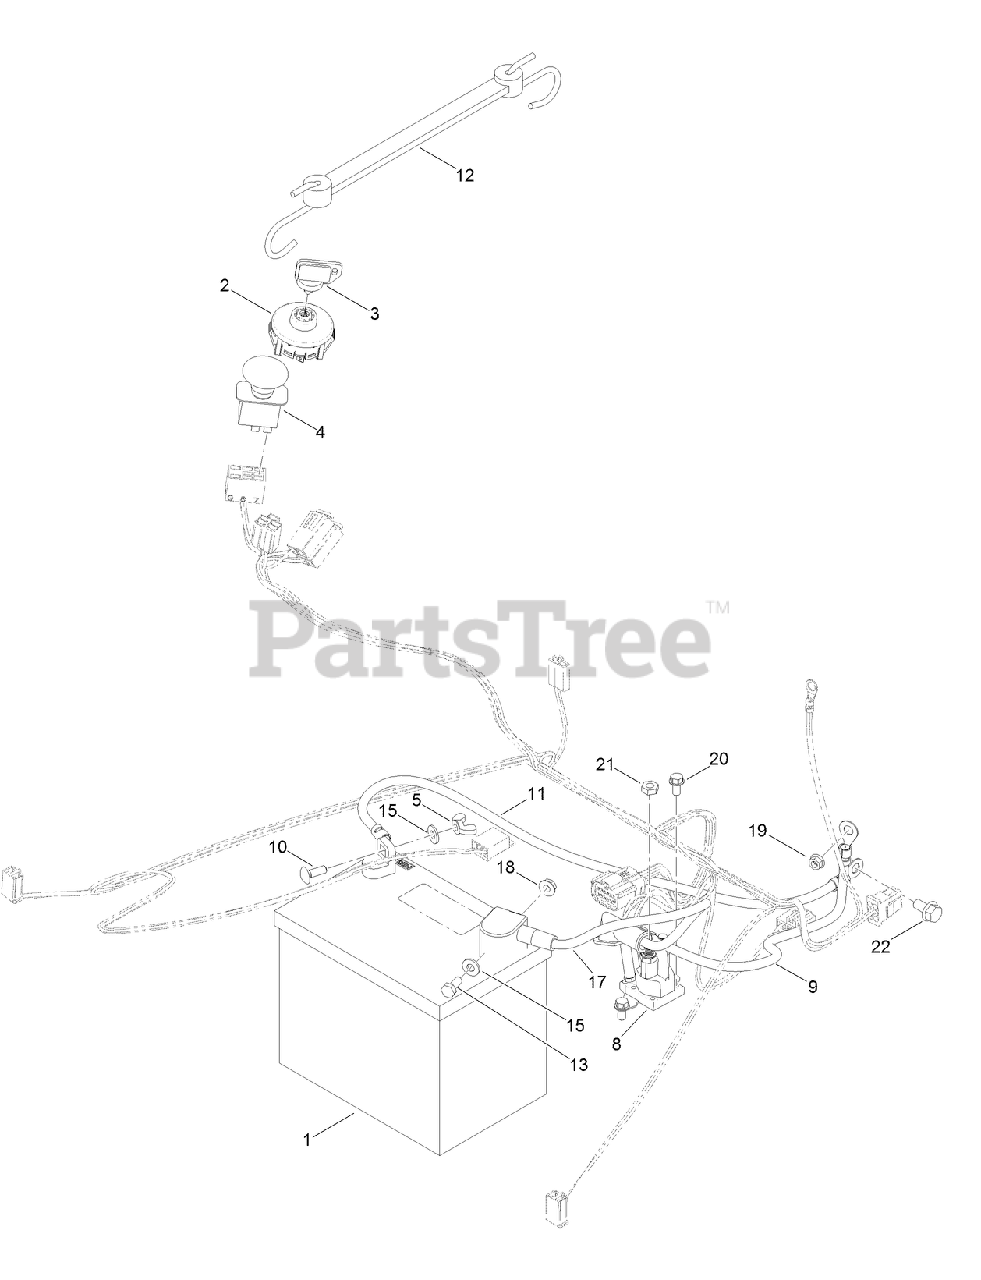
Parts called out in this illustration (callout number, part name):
1	BATTERY
3	KEY-IGNITION
4	SWITCH-PTO
5	NUT-WING
8	SOLENOID
9	CABLE-BATTERY, POSITIVE
10	BOLT-CARR
11	CABLE-BATTERY, BLACK
12	HOLDDOWN-BATTERY
13	SCREW-HH
15	WASHER-FLAT
17	CABLE-BATTERY, RED
18	NUT-HF
19	NUT-HF
20	SCREW-HWH
21	NUT-JAM
22	SCREW-HHF
